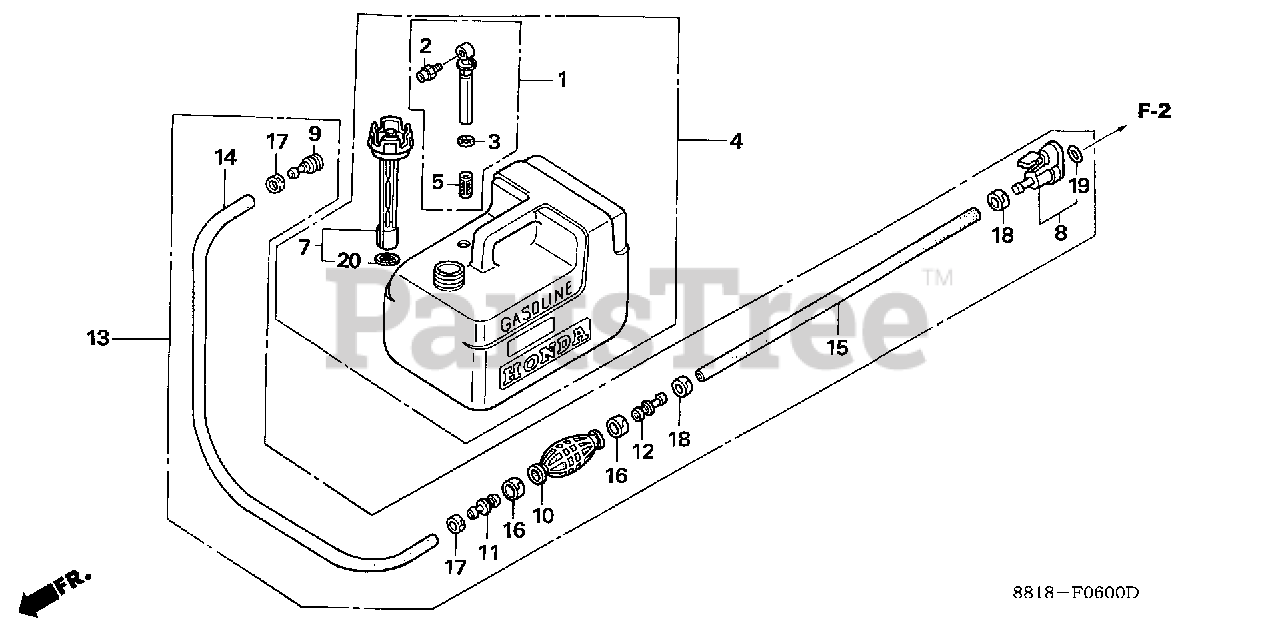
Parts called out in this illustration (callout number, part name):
1	JOINT ASSY., FUEL
2	FITTING, QUICK DISCONNECT
3	O-RING
4	TANK ASSY., FUEL
5	FILTER, FUEL
7	CAP, FUEL FILLER
8	CONNECTOR, FUEL *NH1* (BLACK)
9	CONNECTOR, FUEL
10	BULB, PRIMER
11	VALVE, IN.
12	VALVE, OUTLET
13	TUBE, FUEL *NH1* (BLACK)
14	TUBE, FUEL LONG (7.3X2000)
15	TUBE, FUEL SHORT
16	BAND, TUBE CLIP (20MM)
17	BAND, TUBE CLIP (12.5MM)
18	BAND, TUBE CLIP (11MM)
19	O-RING (5.5MM)
20	GASKET, FUEL CAP
